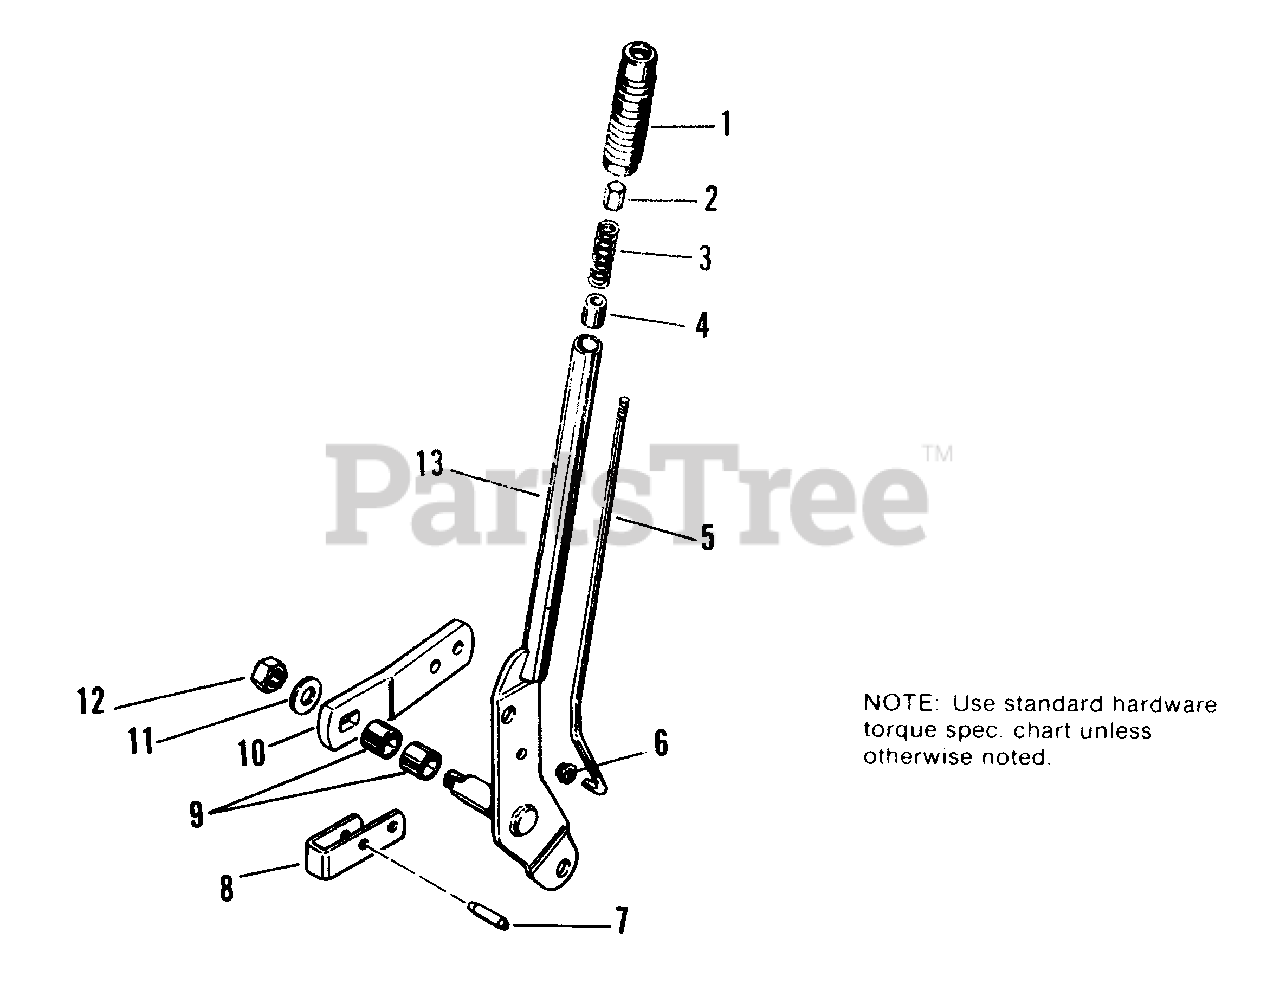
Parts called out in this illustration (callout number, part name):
1	GRIP
2	BUTTON, Thumb
7	PIN, Roll, 3/8 x 1
8	LATCH, Lift Lever
11	WASHER, Plain, 7/16
12	LOCKNUT, Hex, 1/2-13
13	LEVER ASSY., Lift
